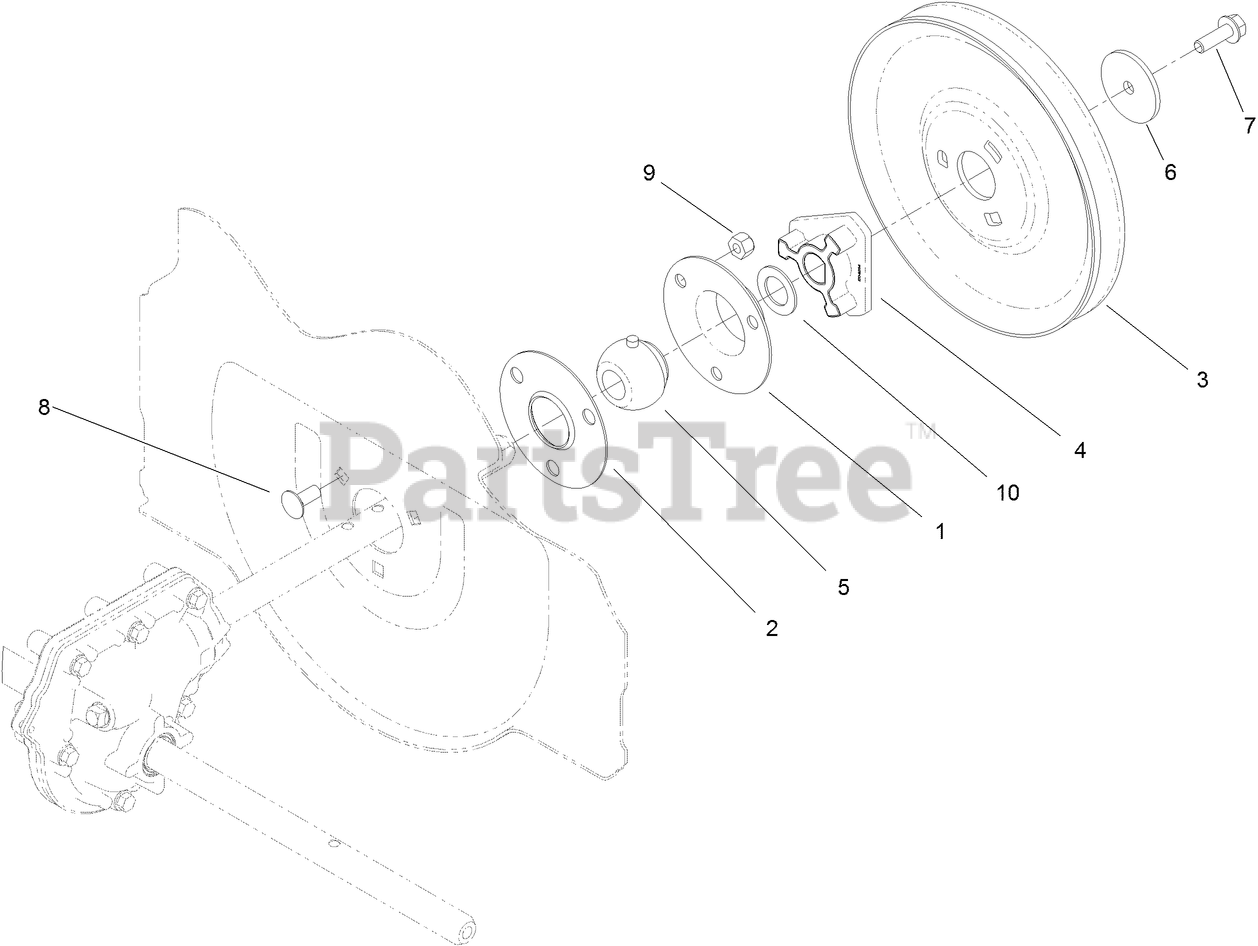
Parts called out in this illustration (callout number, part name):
1	FLANGE-CUP, BEARING
2	FLANGE-CUP, BEARING
3	PULLEY-IMPELLER
4	HUB-IMPELLER, PULLEY
6	WASHER-PLAIN
7	SCREW-HHF
8	SCREW-CARR
9	NUT-LOCK, NI
10	WASHER-THRUST
